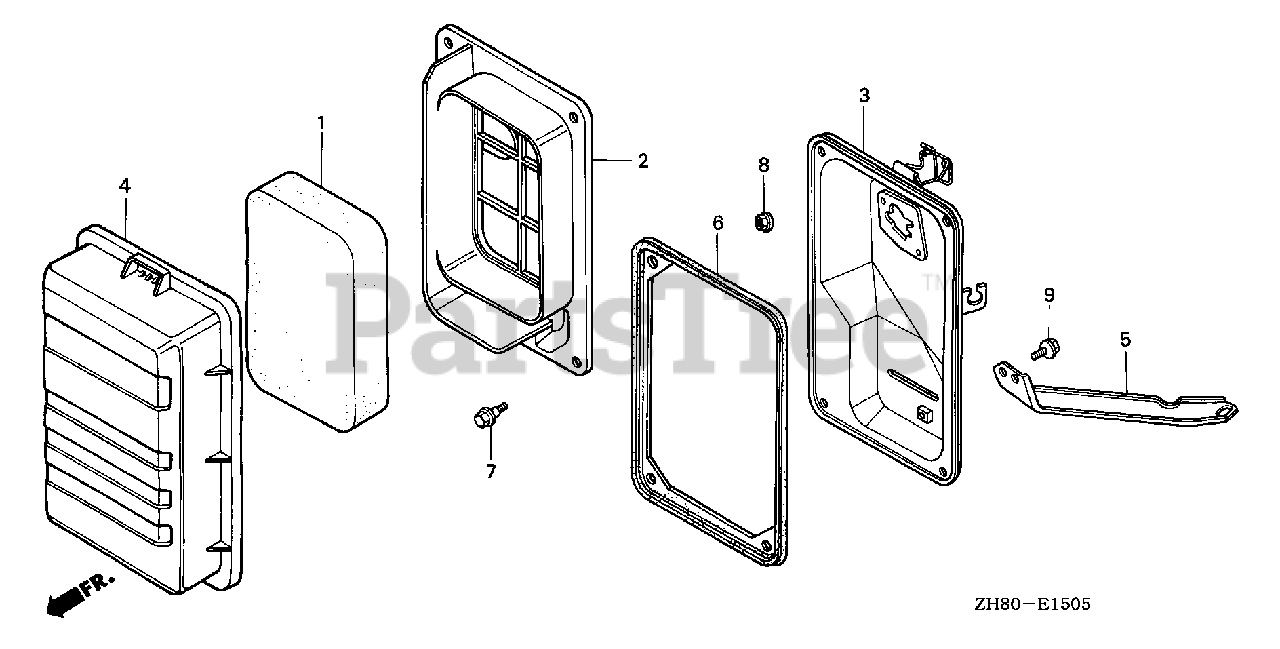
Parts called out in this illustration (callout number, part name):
1	ELEMENT, AIR CLEANER
2	SEPARATOR, AIR CLEANER
3	HOUSING, AIR CLEANER
4	COVER, AIR CLEANER
5	STAY, AIR CLEANER
6	SEAL, AIR CLEANER
7	BOLT, TURN SIGNAL SETTING
8	NUT, FLANGE (6MM)
9	BOLT, FLANGE (6X10)
